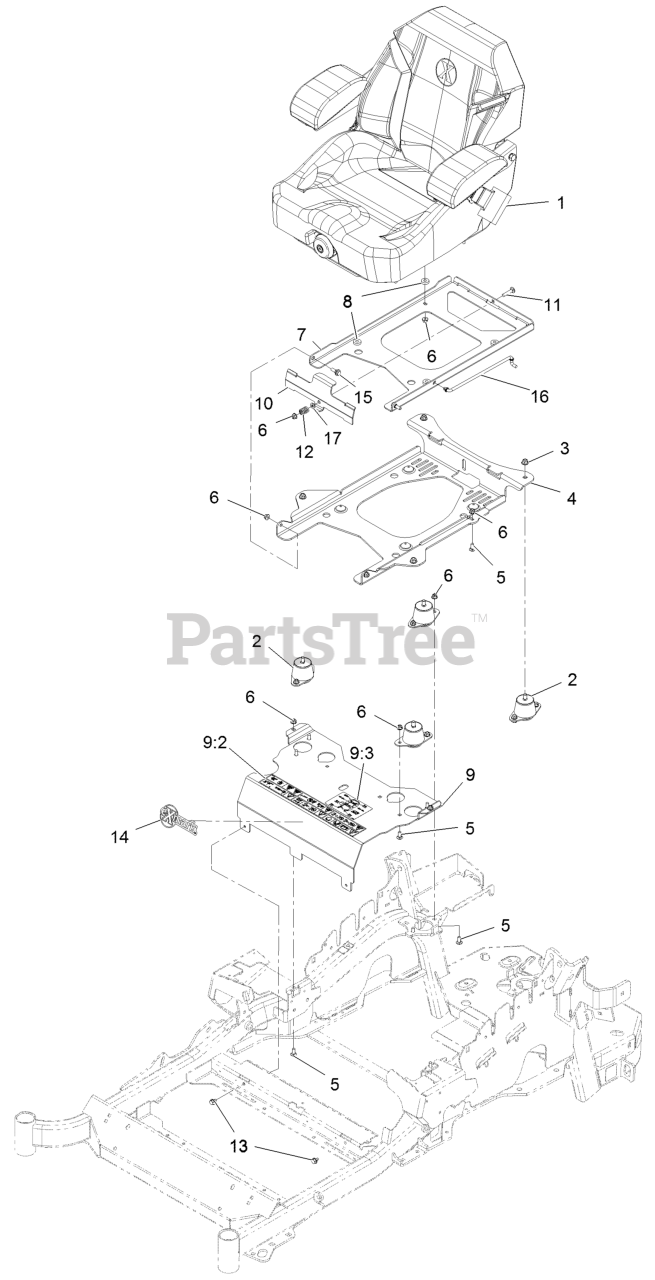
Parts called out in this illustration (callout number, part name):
2	SEAT TRACK SET
3	COVER-BACK 311463VN500
4	COVER-CUSHION 311464VN500
5	KNOB-ADJUSTER
6	COVER-SUSPENSION, BELLOWS
7	SEAT BELT SERVICE KIT
8	KIT-ARM REST SET
9	KIT-ARM REST PADS
10	SWITCH-BAIL
